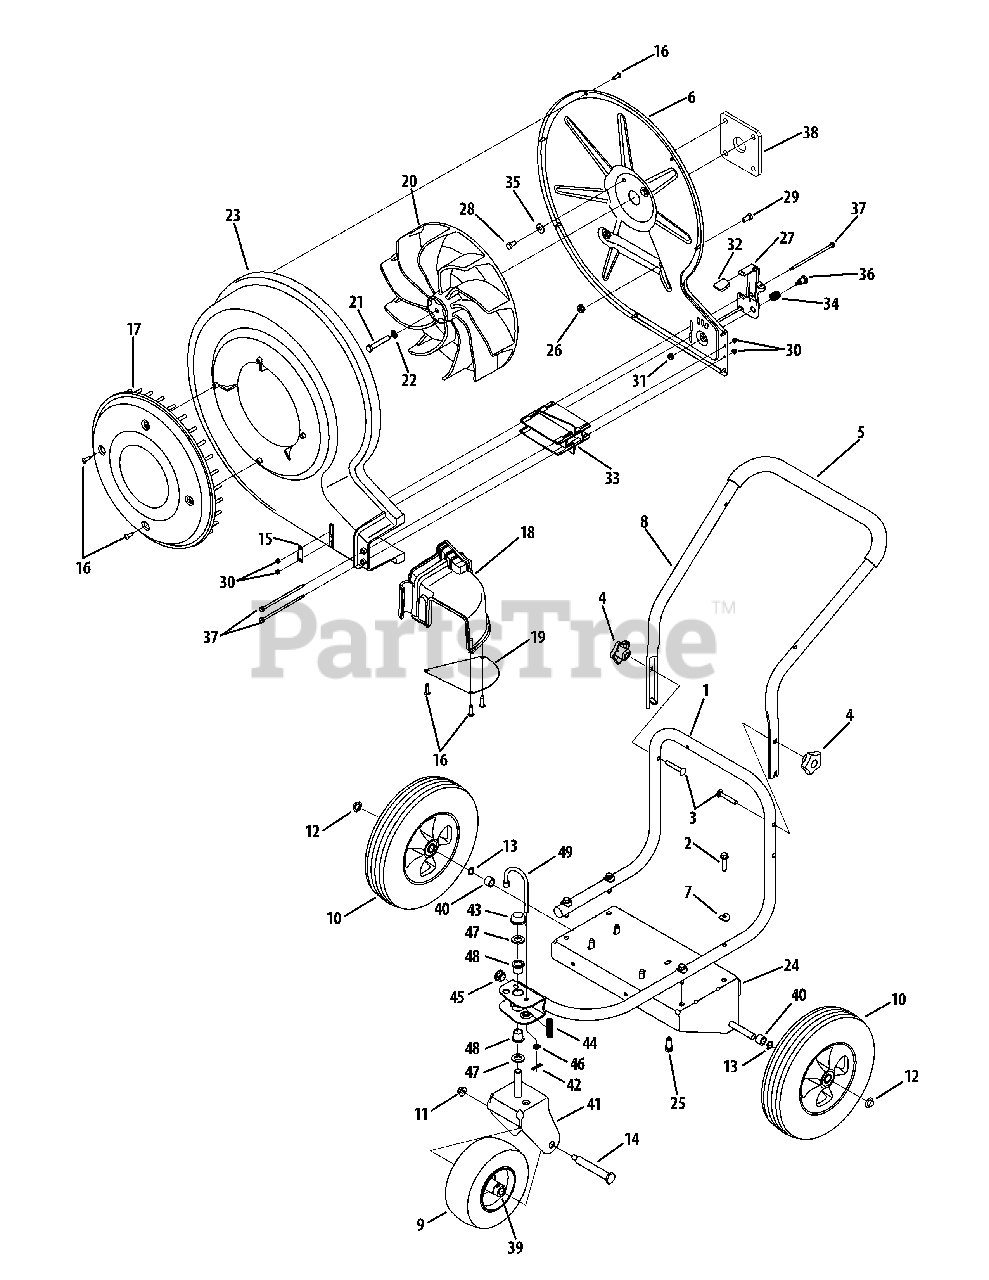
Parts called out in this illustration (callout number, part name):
1	Lower Handle Assembly
2	Hex Screw, 5/16-18 x 1.50
3	Carriage Screw, 5/16-18 x 2.00
4	Star Knob, 5/16-18
5	Foam Grip, .970 x 25
6	Back Plate
7	Saddle Washer, .320 x .93 x .060
9	Wheel, 8 x 3
10	Wheel, 12 x 3, Beige
11	Flange Lock Nut, 3/8-16
12	Push Cap, 1/2"
13	Wave Washer, .510 x .750 x .017
14	Shoulder Screw, .625 x 3.94
16	Hex Screw, 12-16 x .75
17	Blower Cover
18	Chute Assembly
20	Impeller Assembly
21	Hex Screw, 3/8-24 x 2.25
22	Lock Washer, 3/8
23	Blower Housing
25	Sems Screw, 3/8-16 x 1.000
26	Flange Lock Nut, 5/16-18
27	Blower Lever
28	Hex Bolt, 5/16-24 x 1.00
29	Hex Bolt, 5/16-18 x .75
30	Hex Lock Nut, #8-32
31	Flange Lock Nut, 1/4-20
32	Height Adjustment Knob
33	Louver Plate
34	Comp. Spring, .515 x .641 x .95
35	Bell Washer, .340 x .872 x .060
36	Shoulder Screw, .437 x .50 x 1/4-20
37	Shoulder Screw, .18 x 4.8 x 8-32
39	Flange Bearing w/ Fitting
40	Spacer, .525 x .775 x .560
41	Caster Wheel Bracket Assembly
42	Cotter Pin
44	Compr. Sprng., .531 OD x 1.75 Lg
46	Washer, Flat, .330 x .630 x .0635
47	Washer, Flat, .640 x 1.12 x .125
48	Flange Bearing, .631 ID
